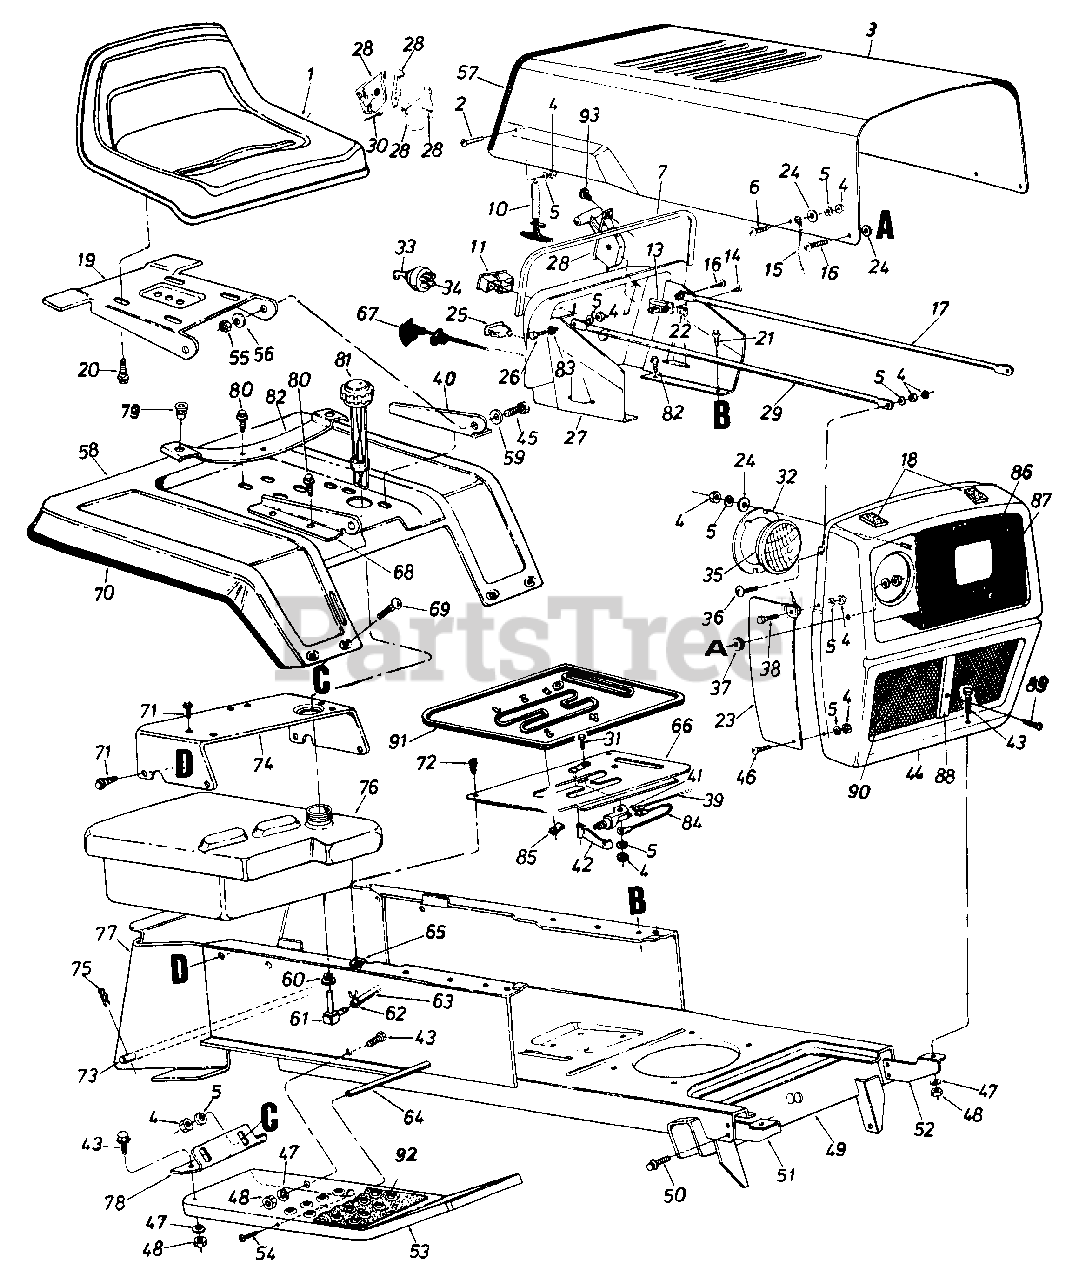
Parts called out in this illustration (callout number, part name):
1	Seat Assembly
1	Seat Ass'y.
2	Truss Mach. Scr. 1/4-20 x .50" Lg.*
5	L-Wash. 1/4" Scr.*
6	Truss Mach. Scr. 1/4-20 x .50" Lg.
7	Vinyl Molding Strip 29"
7	Hex Nylon Scr. 1/2-13 x .75" Lg.
7	Fl-Wash. .50" I.D. x 1.00" O.D. x .09o
10	Hood Latch Ass'y.
11	Ammeter
13	Circuit Breaker 8 Amp.
14	Hex Tap Scr. #10 x .50" Lg.
15	Hood Stop
16	Truss Mach. Scr. 1/4-20 x .75" Lg.
17	Grille Positioning Rod
18	PVC Foam Strip 1/2 x 1.00" x 2.00" Lg.
20	Hex Wash. Hd. AB-Tap Scr. 3/8 x .75" Lg.
21	Hex Thd. Rolling Scr. 1/4" x .50" Lg.
22	Speed Nut #10Z
23	Grille Side Panel R.H.
23	Grille Side Panel L.H.
24	Fl-Wash. 1/4" I.D.
25	Light Switch
26	Truss Hd. Scr. 1/4-20 x 1.00" Lg.
27	Dash Panel Ass'y.
28	Throttle Control Box Comp.
29	Grille Positioning Rod
30	Trottle Control Cable
31	Hex Bolt 1/4-20 x .50" Lg.*
32	Head Lamp Retainer
33	Ignition Key
34	Ignition Switch
35	Head Lamp
36	Truss Machine Scr. 1/4-20 x .75" Lg.*
37	Rubber Wash. .50" I.D. x 1.00 O.D. x .25 Thk.
38	Truss Mach. Scr. 1/4-20 x .50" Lg.*
39	Reverse Lockout Wire Harness
40	Seat Bracket L.H.
41	Safety Switch
42	Switch Actuator Spring Lever
43	Hex Scr. 5/16-18 x .75" Lg.*
44	Grille Ass'y.
45	Hex Bolt 5/16-18 x .75" Lg.*
46	Truss Mach. Scr. 1/4-20 x .50" Lo.
47	L-Wash. 5/16" Scr.
48	Hex Nut 5/16-18 Thd.*
49	Lower Frame Ass'y.
50	Hex Thd. Rolling Scr. 5/16" x.75" Lg.
51	Grille Mount Brkt. R.H.
52	Grille Mount Brkt. L.H.
53	Running Board R.H.
53	Running Board L.H.
54	Truss Mach. Scr. 5/16-18 x .75" Lg.
55	Hex Cent. L-Nut 5/16-18 Thd.
56	Bell-Wash. .34" I.D. x .88 O.D.
57	Vinyl Moulding Strip 30"
58	Fender Ass'y. R.H.
58	Fender Ass'y. L.H.
59	Bell-Wash. .34" I.D. x .88" O.D.
60	Bushing
61	90ø Nipple
62	Hose Clamp 3/8"
63	Gas Line 46" Lg.
64	Running Board Rod
65	Speed Nut #10-24
66	Transmission Cover Ass'y.
67	Choke Control Comp.
68	Seat Bracket R.H.
69	Carr. Bolt 1/4-20 x .50" Lg.
70	Trim Strip 81" Lg.
71	Hex Thd. Rolling Scr. 5/16-24 x .75" Lg.
72	Truss Hd. Scr. #10 x .50" Lg.
73	Hitch Rod
74	Seat Mounting Channel
75	Internal Cotter Pin
76	Gas Tank
77	Hitch Plate
78	Fender Brkt. R.H.
80	Hex Wash. Hd. Self-Tap Scr. 5/16-18 x .50" Lg.
81	Gas Gauge
82	Seat Spring
83	External Wash. 1/4" I.D.
84	Electric Wire
85	Speed Nut 1/4" Stud
86	Headlight Bezel
87	Hex Wash. Hd. F-Tap Scr. #8-32 x .38" Lg.
88	Center Moulding
89	Truss Mach. Scr. #10-24 x .62" Lg.
90	Grille Screen
91	Transmission Cover
92	Foot Pad
93	Truss Mach. AB-Tap Scr. #10 x .50" Lg.
